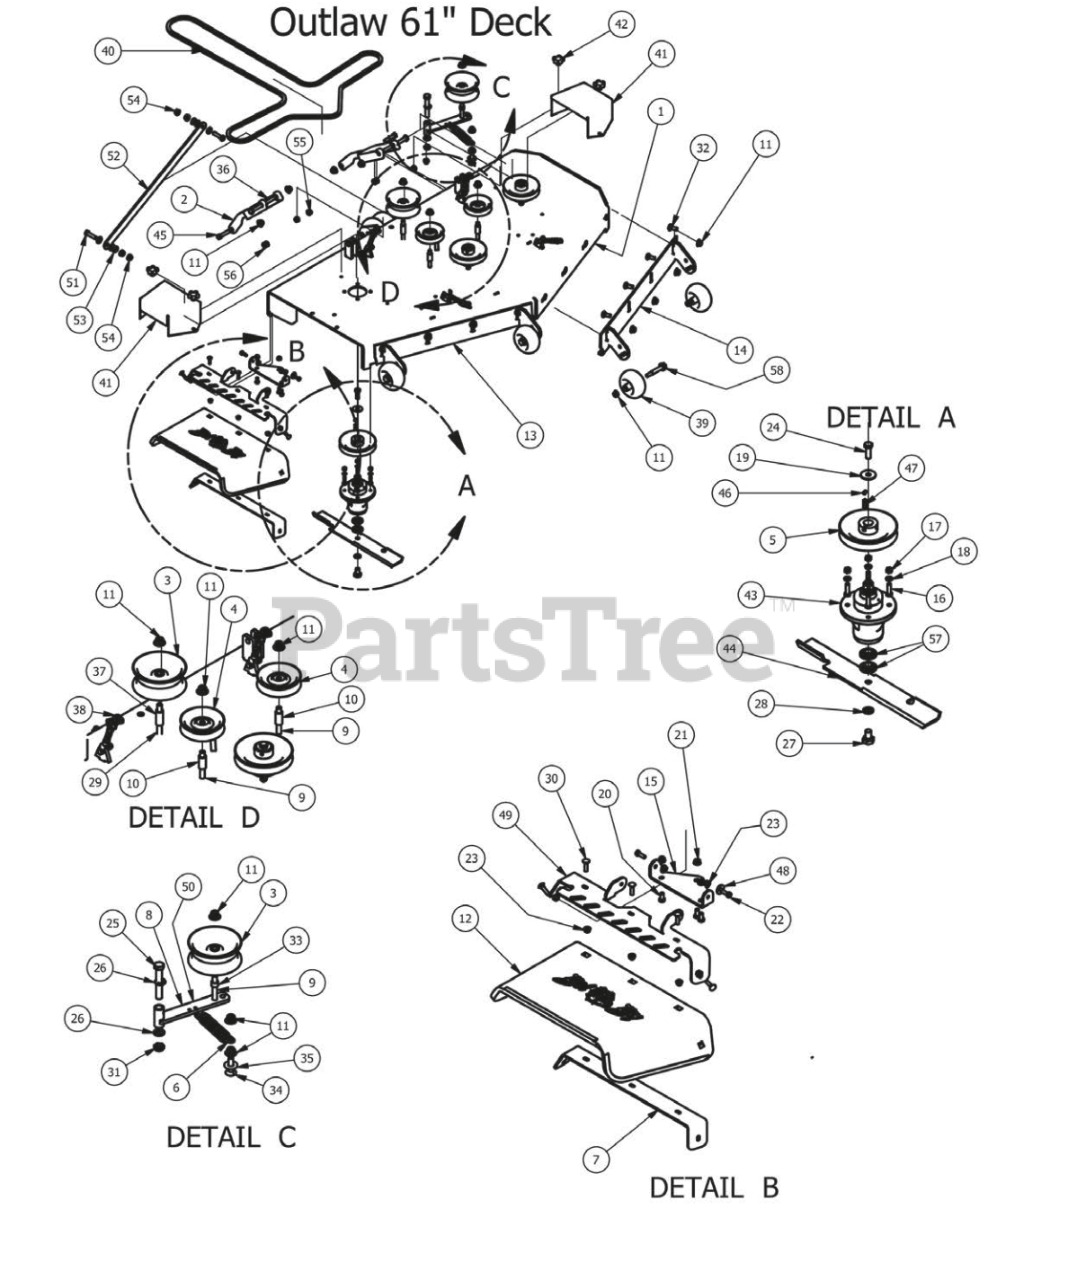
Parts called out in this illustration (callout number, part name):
1	61" Outlaw (Deck Only)
2	Deck Arm Assembly
3	5 3/4 Flat Idler-32FI-92-008 Pulley
4	4 3/4" Idler Pulley
5	6 1/4" Drive Pulley
6	2009 Deck/Pump Idler Spring
7	60" Lower Hanger
8	Deck Idler Bracket
9	1/2 x 3 1/2 Flange Bolt Grade 8
10	Pulley Spacer
11	1/2-13 Nylon Insert Flange Nut
12	Rubber Discharge Chute
13	61 Outlaw Adjustable Deck Front (Left)
14	61 Outlaw Adjustable Deck Front (Right)
15	Discharge Chute Hanger (deck mounted)
16	3/8" x 1 1/4" Hex Bolt
17	3/8-16 Hex Nuts Zinc
18	3/8 Lockwasher Zinc
19	1/2 Belleville Washer
20	3/8" x 3/4" Hex Bolt
21	3/8" Flange Nut
22	5/16" x 1" Bolt
23	5/16" Flange Nut Zinc W/Serrations
24	1/2"-20 x 1 1/2 - Grade 5 Fine Thread Bolt
25	5/8" x 4" Hex Bolt
26	.635 ID Plastic Washer
27	5/8" x 1 1/2" Grade 8 Bolt
28	5/8" Lock Washer
29	1/2" x 4" Bolt (Grade 8)
30	5/16" x 1 1/4" Carriage Bolt
31	5/8" Nylock (1/2 Jam)
32	1/2" x 1 1/4 Carriage Bolt
33	Spacer 3/4 OD X 1/2 ID X.75
34	1/2 x 2" Carriage Bolt
35	1/2" Flat Washer
36	1/2" x 5 1/2" Bolt
37	1 3/4" Pulley Spacer
38	2- Link Adjustable Deck Hange
39	Deck Wheel
40	B178 Belt For 61 Inch Outlaw
41	Pulley Cover
42	5/16" Knob
43	Double Bearing Spindle
44	61 inch Fusion Blade
45	1/2-13X 2-1/4 GR Hex Bolts
46	5/16 Set Screw
47	1/4" x 1" Key
48	.360 ID Plastic Washer
49	60" Upper Hanger Plate
50	Deck Idler Assembly-parts of Assembly 8,11,3,33,9
51	1/2" x 13-2" GR 5 Hex Bolt
52	Panhard Linkage Bar
53	.505 Nylon Spacer
54	1/2" Flange Nut
55	Flange Bushing For Deck Arm upper
56	Flange for Lower Deck Arm
57	Double Bearing For Spindle
58	Deck Wheel Bolt-2011 Outlaw
